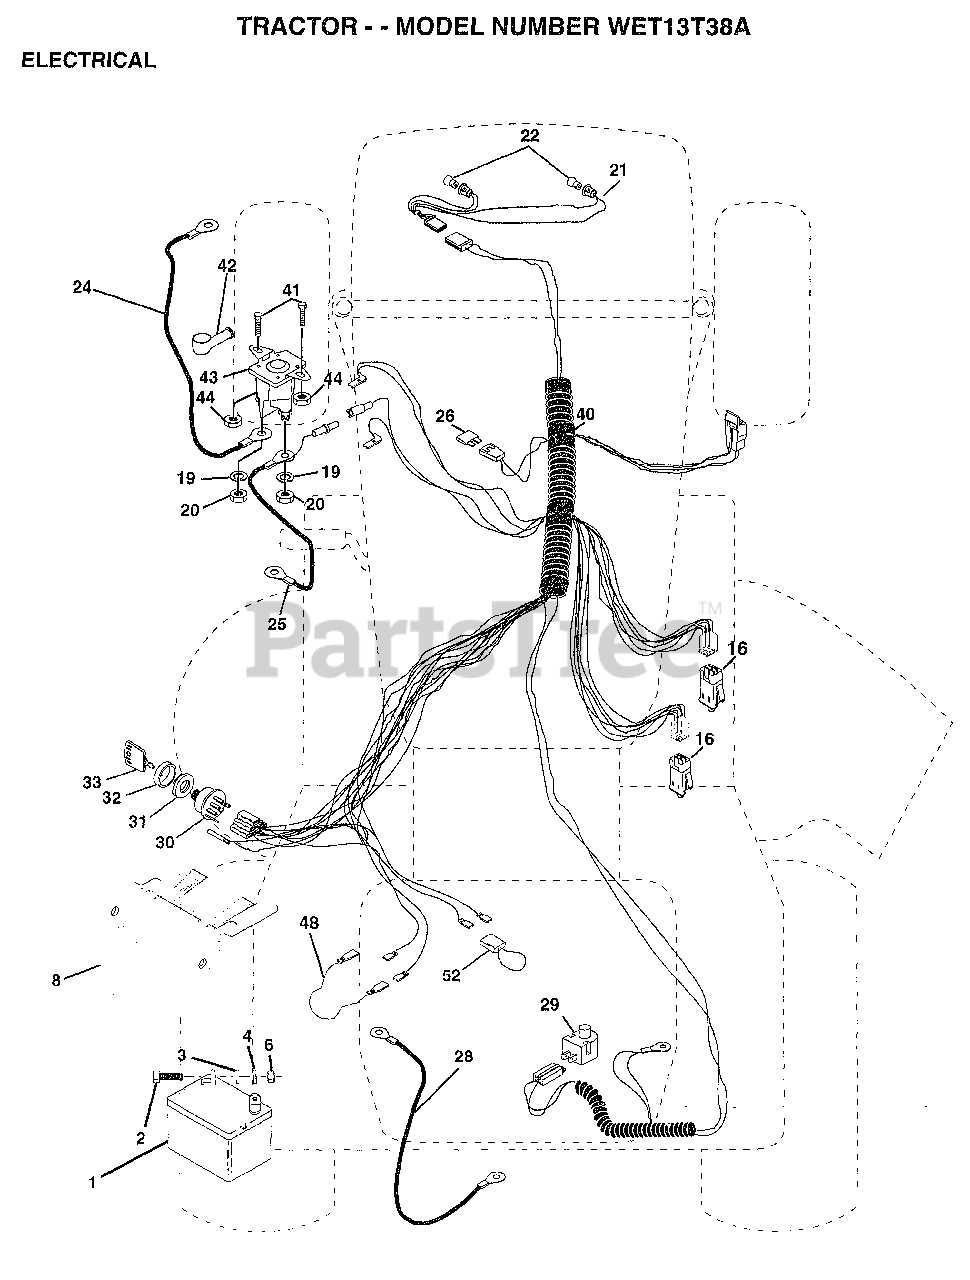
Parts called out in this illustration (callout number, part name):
3	WASHER
4	LOCKWASHER
8	"CASE,BATTERY.MECH"
16	SWITCH INTERLOCK
20	NUT
21	"HARNESS,LIGHT SOC"
22	HEADLAMP BULB
24	CABLE ASM.
25	CABLE.BTRY.6GA.RD
26	FUSE HYT
28	CABLE T
29	SWITCH SEAT
30	SWITCH IGN 4POS
31	NUT IGNITION
32	COVER KEY SWITCH
33	KEY
40	HARNESS-IGNITION
41	BOLT HXHD FIN
44	NUT HXKEP 1/4X20
48	ADAPTER AMMETER
52	PROTECTION LOOP
